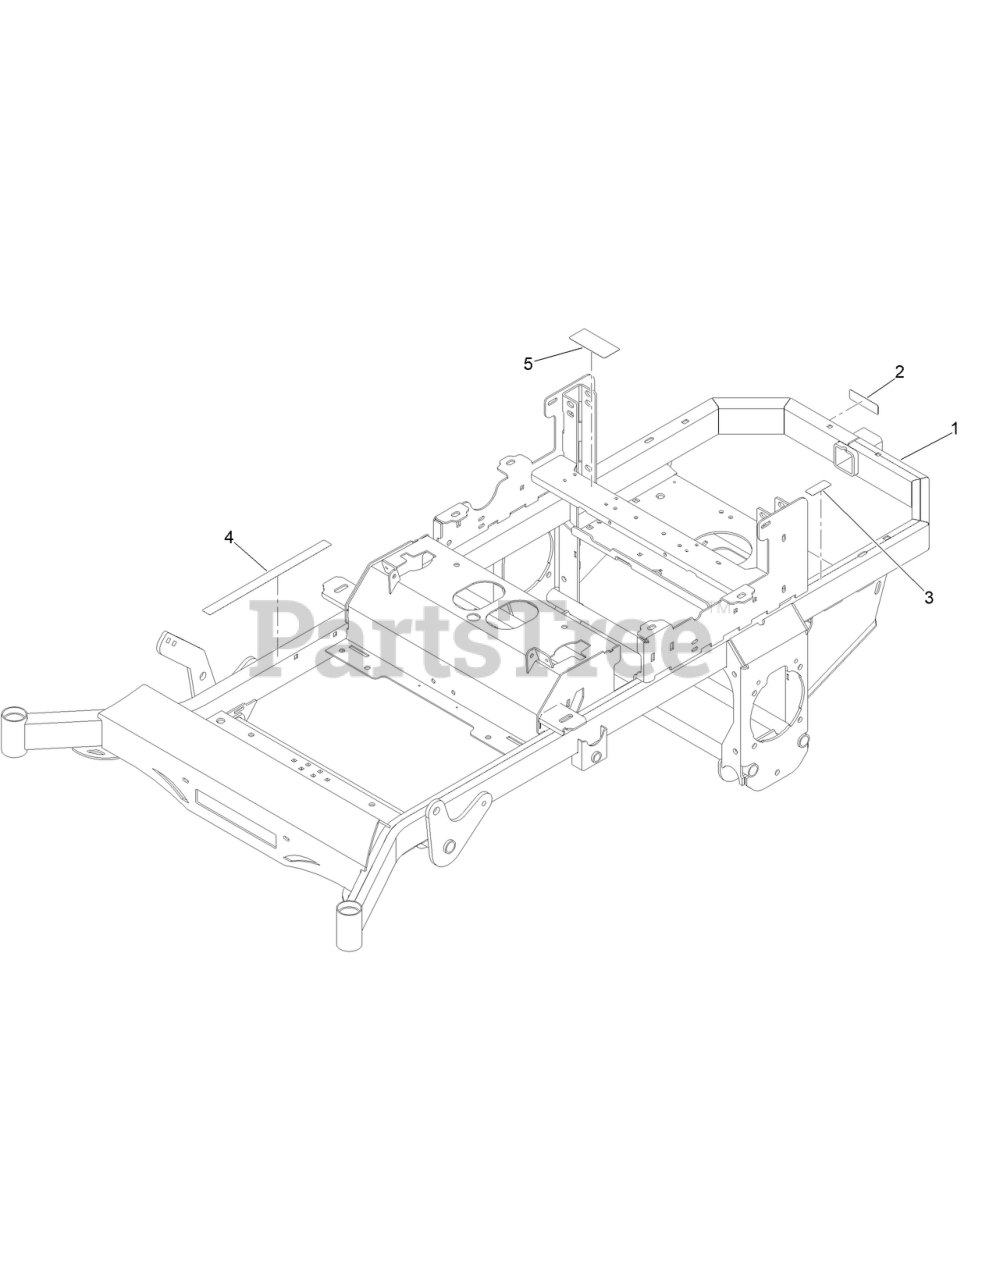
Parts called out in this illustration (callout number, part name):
1	FRAME ASM - RT PAINTED
2	DECAL-HITCH
3	DECAL-HOT SURFACE
4	DECAL-WARNING(AURORA)
5	DECAL-ROTATING FAN HAZARD
